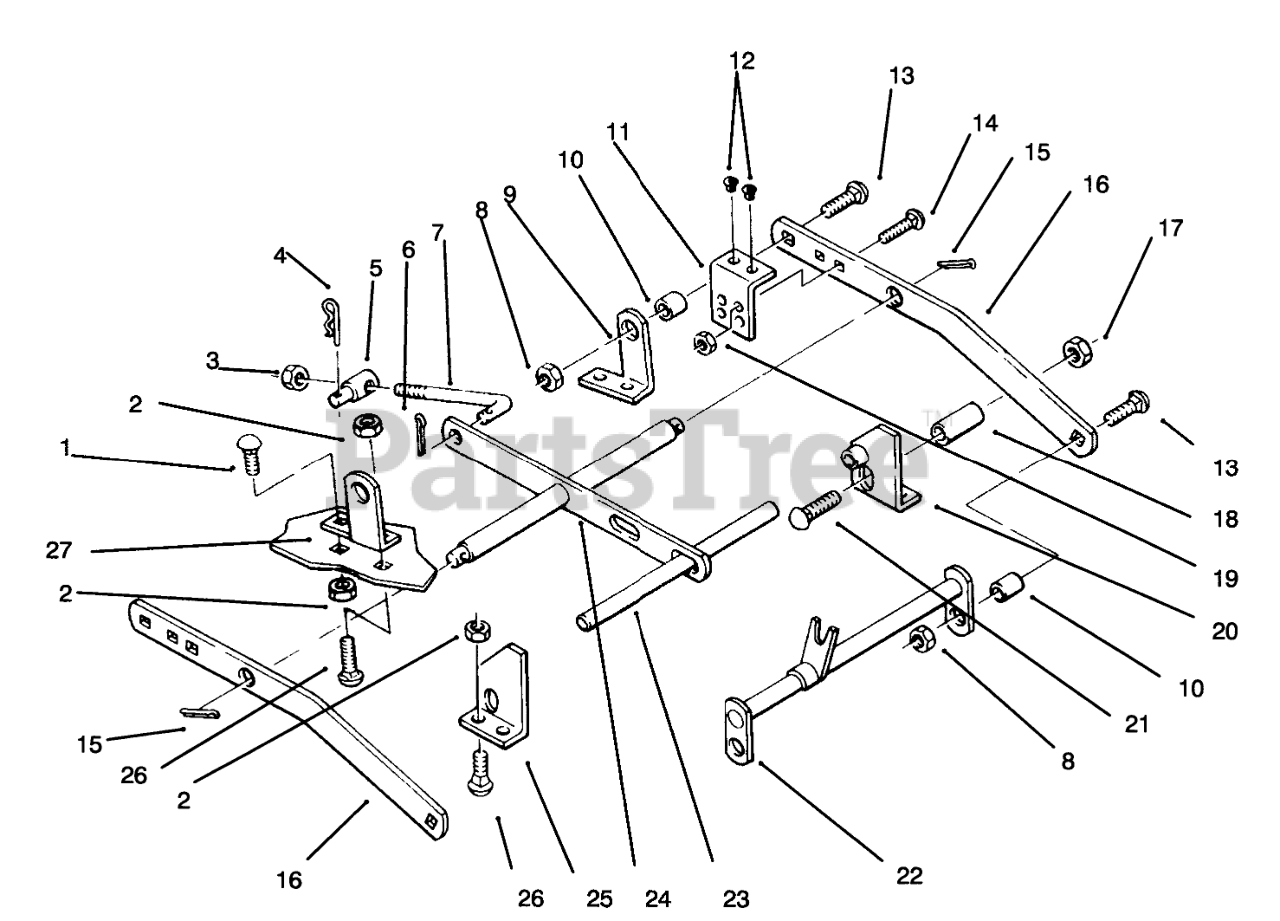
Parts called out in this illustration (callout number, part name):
1	BOLT-CARR
2	NUT-HEX
3	NUT-LOCK, NI
4	Hairpin
5	TRUNNION-LIFT
6	PIN-COTTER
7	ROD-LEVEL ADJUST
8	LOCKNUT-FLANGE
9	LH Rear Bracket
10	SPACER
11	Bumper-Metal
12	BUMPER-RUBBER
13	BOLT-CARR
14	BOLT-CARR
15	PIN-COTTER
16	Bar Draft
17	Nut
19	Nut
20	Front Bracket LH
21	BOLT-CARR
22	Hitch
23	Front Shaft
24	Leveler
25	Front Bracket RH
26	SCREW-CARR
27	Rear Bracket RH
